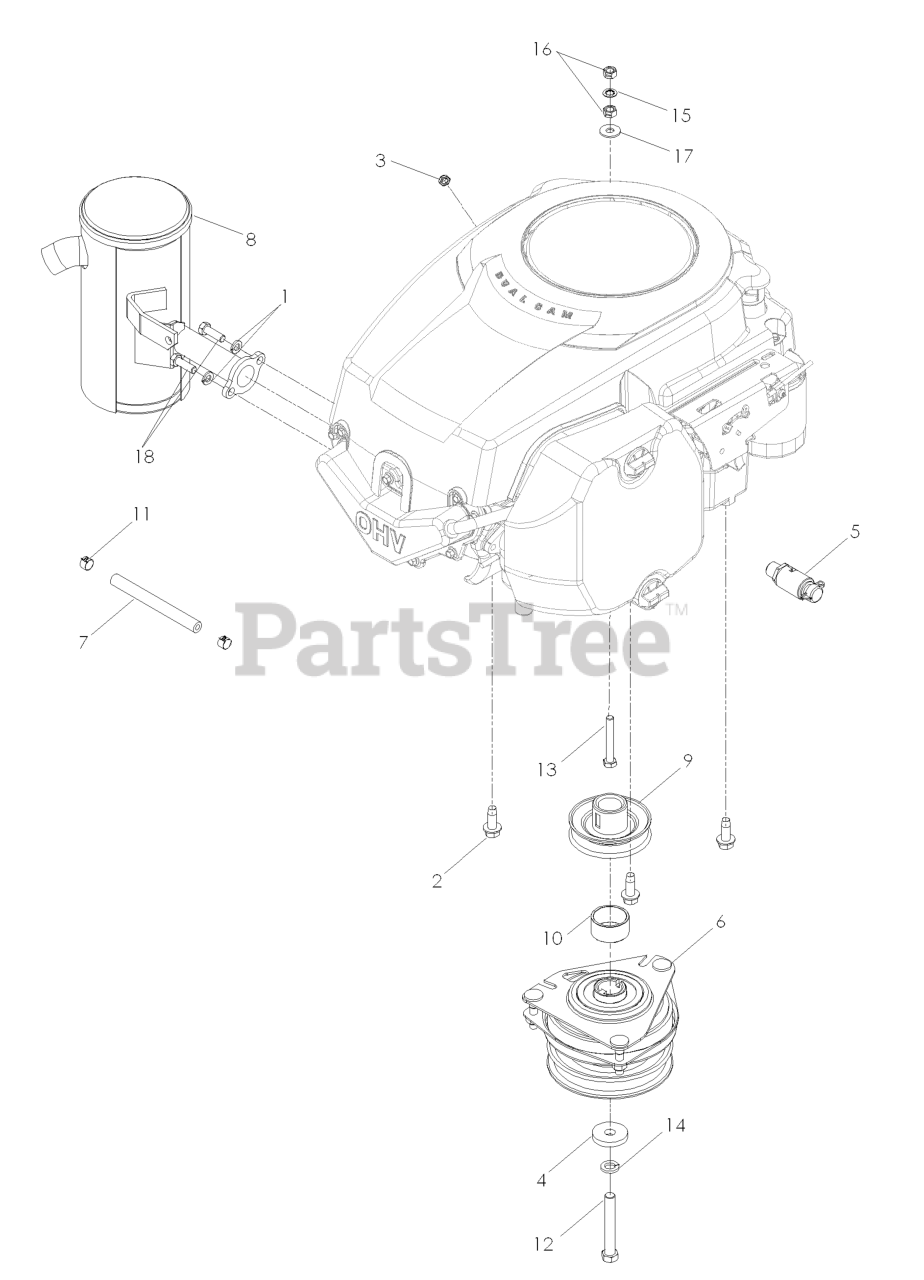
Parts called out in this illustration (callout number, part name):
1	WASHER.LOCK.HVY.HLCL.SPR.5/16
2	BOLT 3/8-16 X 1.0
3	JAM NUT 1/4C (2 2 PW01)
4	CLUTCH, WASHER
5	OIL DRAIN FITTING
6	CLUTCH 90 FT/LB OGURA
7	FUEL LINE 5"
9	PULLEY, ENGINE
10	SPACER, ENGINE - PULLEY
11	HOSE CLAMP
12	HEX SCREW 7/16-20 X 3
14	WASHER 7/16 LOCK
15	WASH 5/16X19/32X1/32 ITLW ZD
16	NUT 5/16C CENTERLOCK
17	WASHER 5/16 FLAT
18	HCS 5/16C X 1
